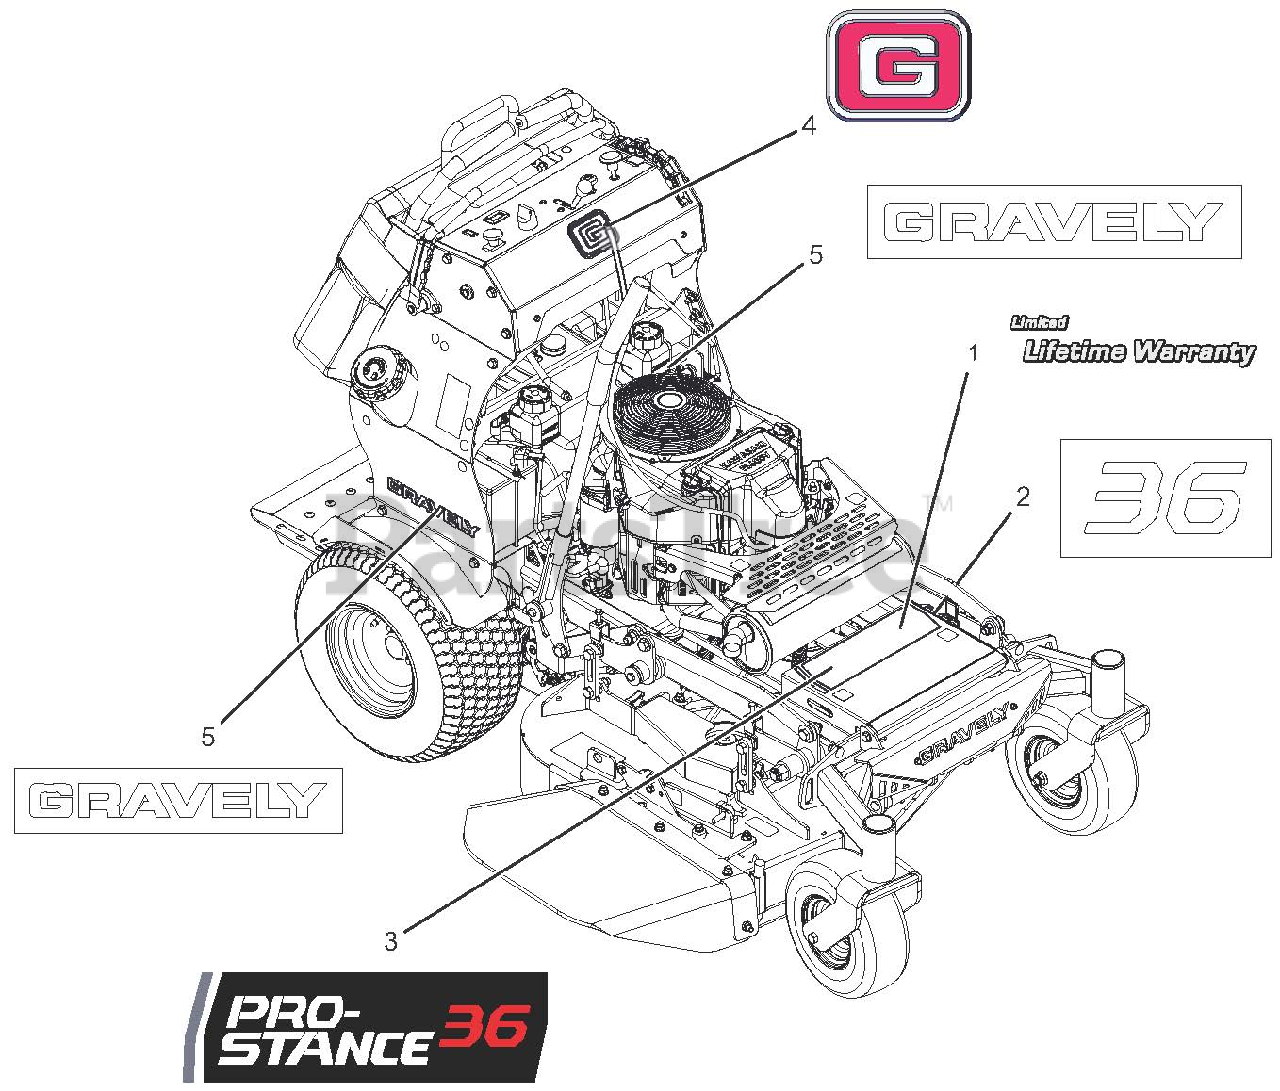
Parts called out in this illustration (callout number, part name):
1	DECAL, LIMITED LIFETIME WARR
2	DECAL, 36"
3	DECAL, PROSTANCE 36
4	DECAL, GRAVELY BRAND
5	DECAL, 9.5" GRAVELY LOGO
